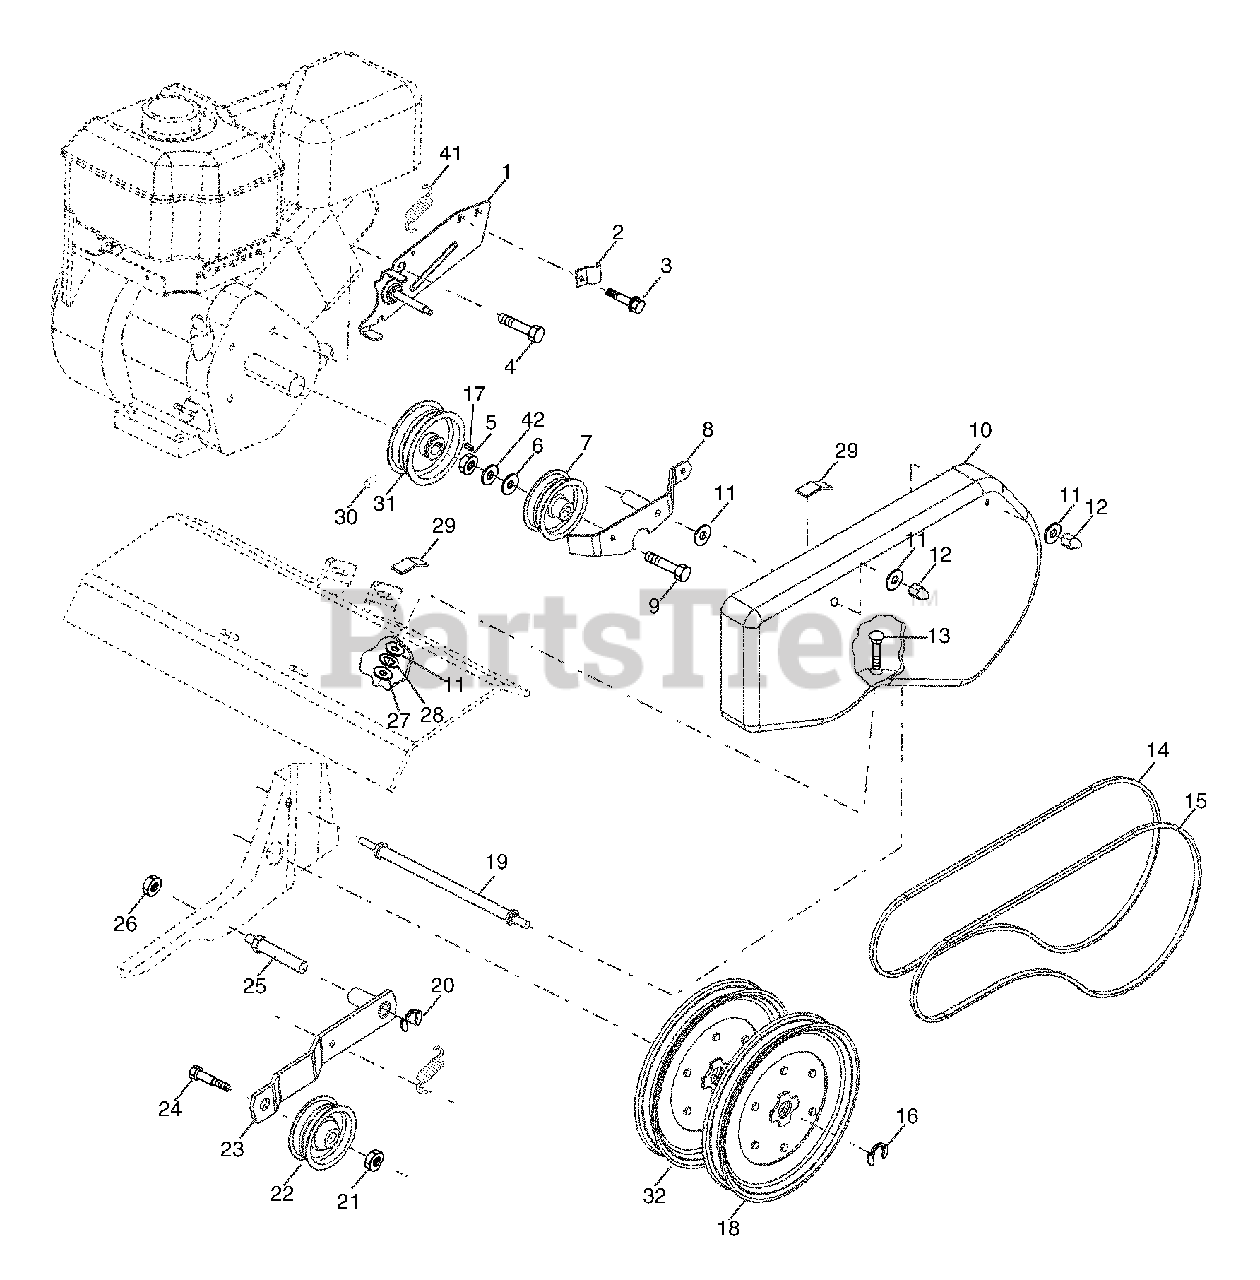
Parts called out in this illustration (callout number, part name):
1	Assembly, Bracket, Belt Guard
2	Clip, Cable
3	Screw, Hex, Washer Hd., Slotted, Thd. Cutting #10-24 x 1/2 Type D
4	Bolt, Hex 1/2-20 x 3/4
5	Nut, Hex Lock 3/8-16
6	Washer 13/32 x 13/16 x 16 Ga.
7	Pulley, Idler, Reverse
8	Assembly, Arm, Reverse Idler
9	Bolt, Hex 3/8-16 x 1-3/4
11	Washer 9/32 x 5/8 x 16 Ga.
12	Nut, Cap 1/4- 20
13	Bolt, Carriage 1/4-20 x 3/4
14	V-Belt (Forward Motion)
15	V-Belt (Reverse)
16	Ring, Retainer
17	Key, Square
18	Pulley, Flat, Trans.
19	Bolt, Belt Guard
20	Ring, Klip
21	Nut, Hex, Jam 3/8-16
22	Pulley, Idler
24	Bolt, Hex 3/8-16 x 1-1/4
25	Shaft, Idler Arm
26	Nut, Hex, Jam 5/16-18
27	Nut, Fin Hex 1/4-20
28	Washer LK Hvy Helical 1/4
29	Pad, Idler
30	Screw, Set, Socket, Headless C.P. 1/4-20 x 1/4
31	Sheave, Engine
32	Pulley, V-Groove, Trans.
41	Spring
42	Spacer
